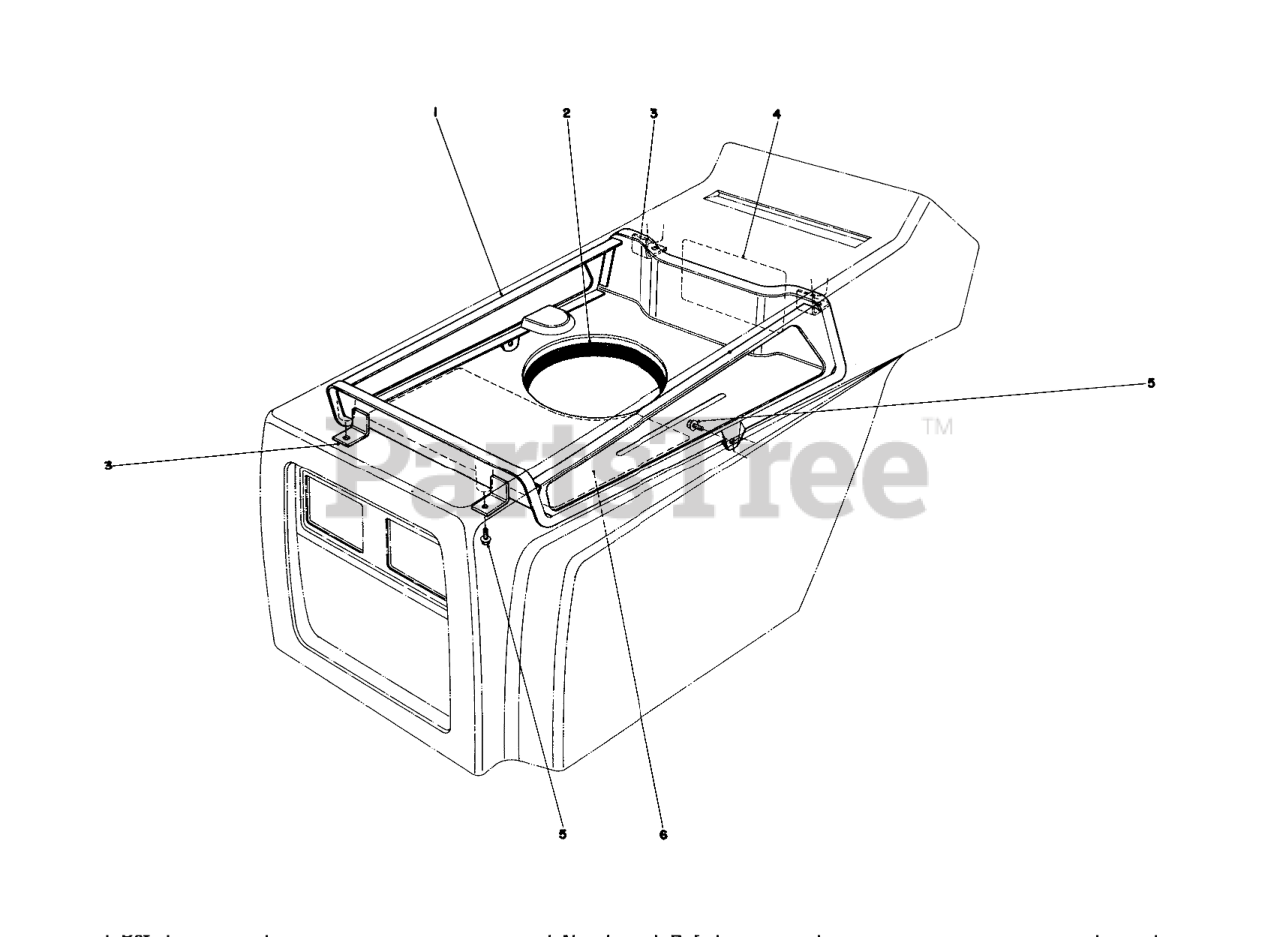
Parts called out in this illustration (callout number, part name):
1	Duct Hood
2	Seal Engine
3	Bracket Duct Support
4	Decal-Belt Change
5	SCREW-HWHTF
6	Decal Service
